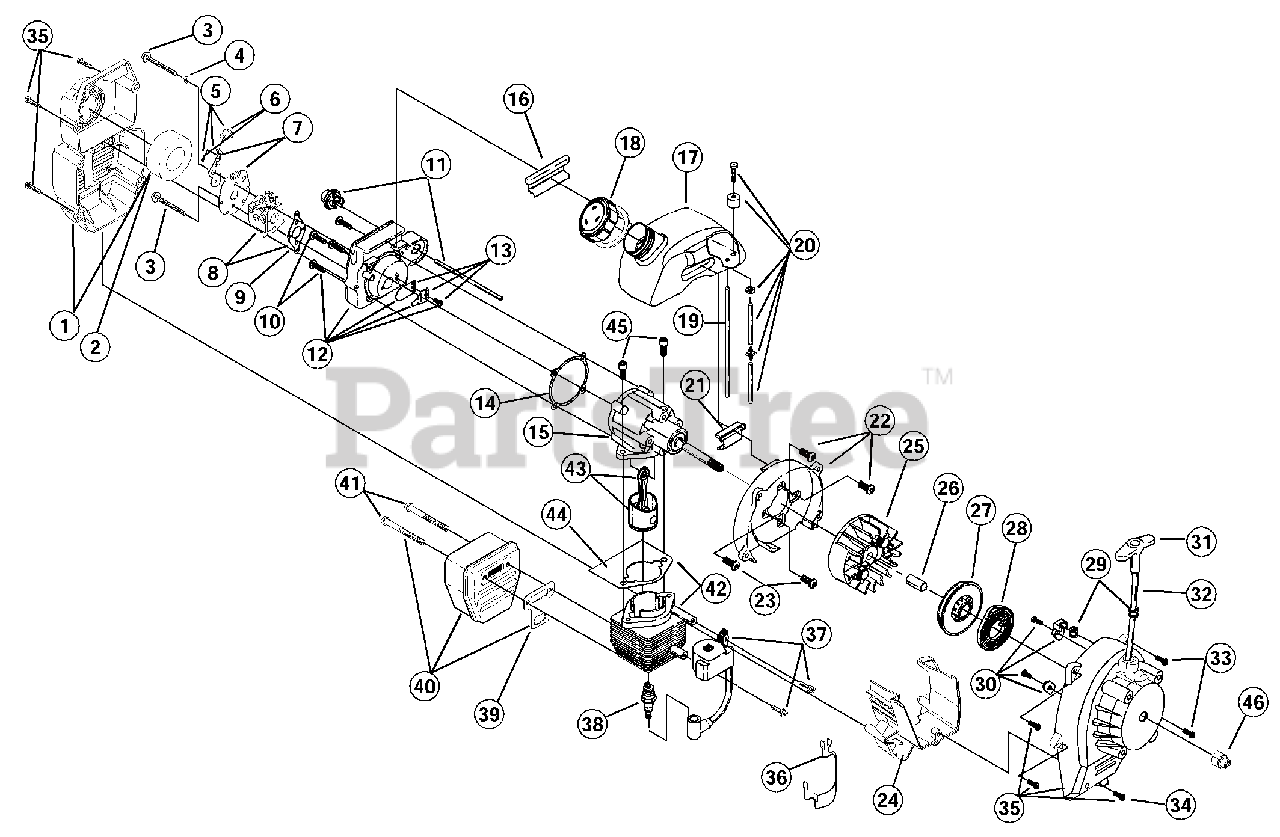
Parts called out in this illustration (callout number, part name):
1	Air Cleaner/Muffler Cover Assembly
2	Air Cleaner Filter
3	Carburetor Mounting Screw Assembly
4	Wavey Washer
5	Choke Lever Assembly
6	Choke Knob and Screw
7	Choke Lever and Plate
8	Carburetor Assembly W/Limiter Caps
9	Carburetor Gasket
10	Carb Mount Screw
11	Primer and Hose Assembly
12	Carb Mount Assembly
13	Reed Assembly
14	Carburetor Mount Gasket
15	Crank Case Service Assembly
16	Rear Mounting Pad
17	Fuel Tank Assembly
18	Fuel Cap Assembly
19	Fuel Return Line
20	Fuel Line Assembly
21	Front Mounting Pad
22	Shroud Assembly
23	Shroud Screw
24	Shroud Extension
25	Flywheel Assembly
27	Recoil Pulley Assembly
28	Recoil Spring
29	Rope Guide
30	Pulley Retainer Assembly
31	Pull Handle
33	Housing Screw
34	Cover Screw
35	Starter Housing Assembly
36	Wire Lead Assembly
37	Module Assembly
38	Spark Plug
39	Exhaust Gasket
40	Muffler Assembly
41	Muffler Mounting Bolt Assembly
42	Cylinder Assembly
43	Piston and Rod Assembly
44	Cylinder Gasket
45	Cylinder Bolt
46	Crankshaft Extension
